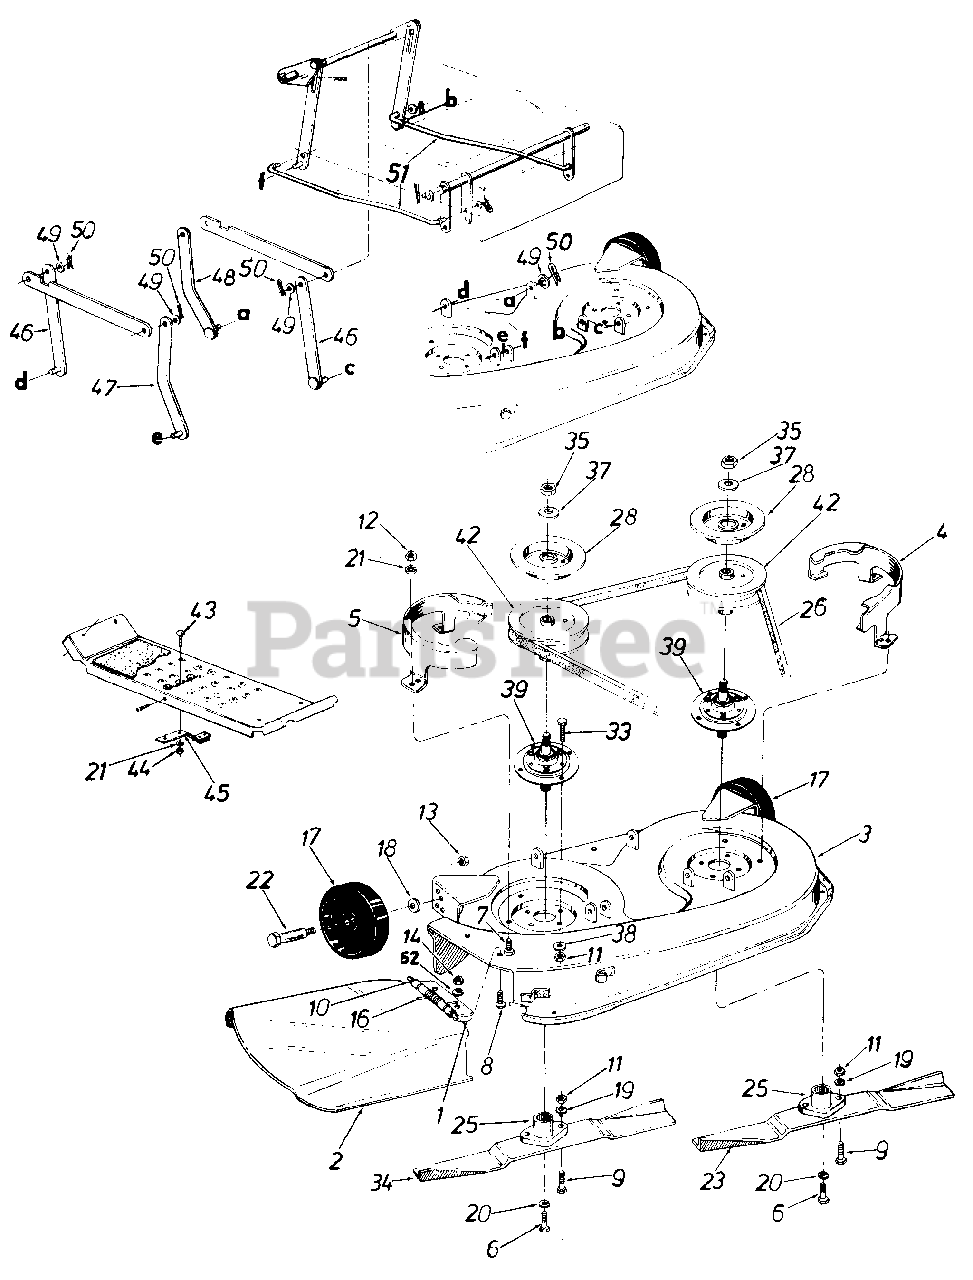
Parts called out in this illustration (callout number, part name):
1	Chute Bracket
2	Chute Deflector
3	38" Deep Deck Ass'y.
6	Hex Bolt 3/8-24 x 1.00"
7	Hex Bolt 1/4-28 x .62"
8	Truss Mach. Scr. 1/4-20 x .75"
9	Hex Bolt Special 5/16-24 x 1 .O"
10	Hinge Pin
11	Hex Nut 5/16-24 Thd.
12	Hex Nut 1/4-28 Thd.
13	Hex Top L-Nut 3/8-16 Thd.
14	Hex Jam Nut 1/4-20 Thd.
16	Torsion Spring
17	Deck Wheel-5"
18	Bell-Wash. .40" I.D. x .88" O.D.
19	L-Wash. 5/16" I.D.
20	L-Wash. 3/8" I.D.-H.D.
21	L-Wash. 1/4" I.D.
22	Shld. Bolt .498" Dia. x 1.53
23	High-Lift Blade-L.H.
25	Blade Adapter
26	5L V-Belt
28	Brake Disc
33	Rib Neck Bolt 5/16-24 x 1.05" Lg.
34	High-Lift Blade-R.H.
35	Hex Jam Nut 5/8-18 Thd.
37	L-Wash. 5/8" I.D.*
38	L-Wash. 5/16" I.D.
39	Blade Spindle Ass'y. Comp.
42	5" Dia. Pulley
43	Carr. Bolt 1/4-20 x .62"
44	Hex Nut 1/4-20 Thd.
45	Blade Brake Ass y.
46	Link Deck Hanger Ass'y.
47	Link Deck Hanger Ass'y.
50	Inter. Cotter Pin .50" Dia.
51	Stabilizer Rod
52	Bell-Wash. 1/4" I.D.
